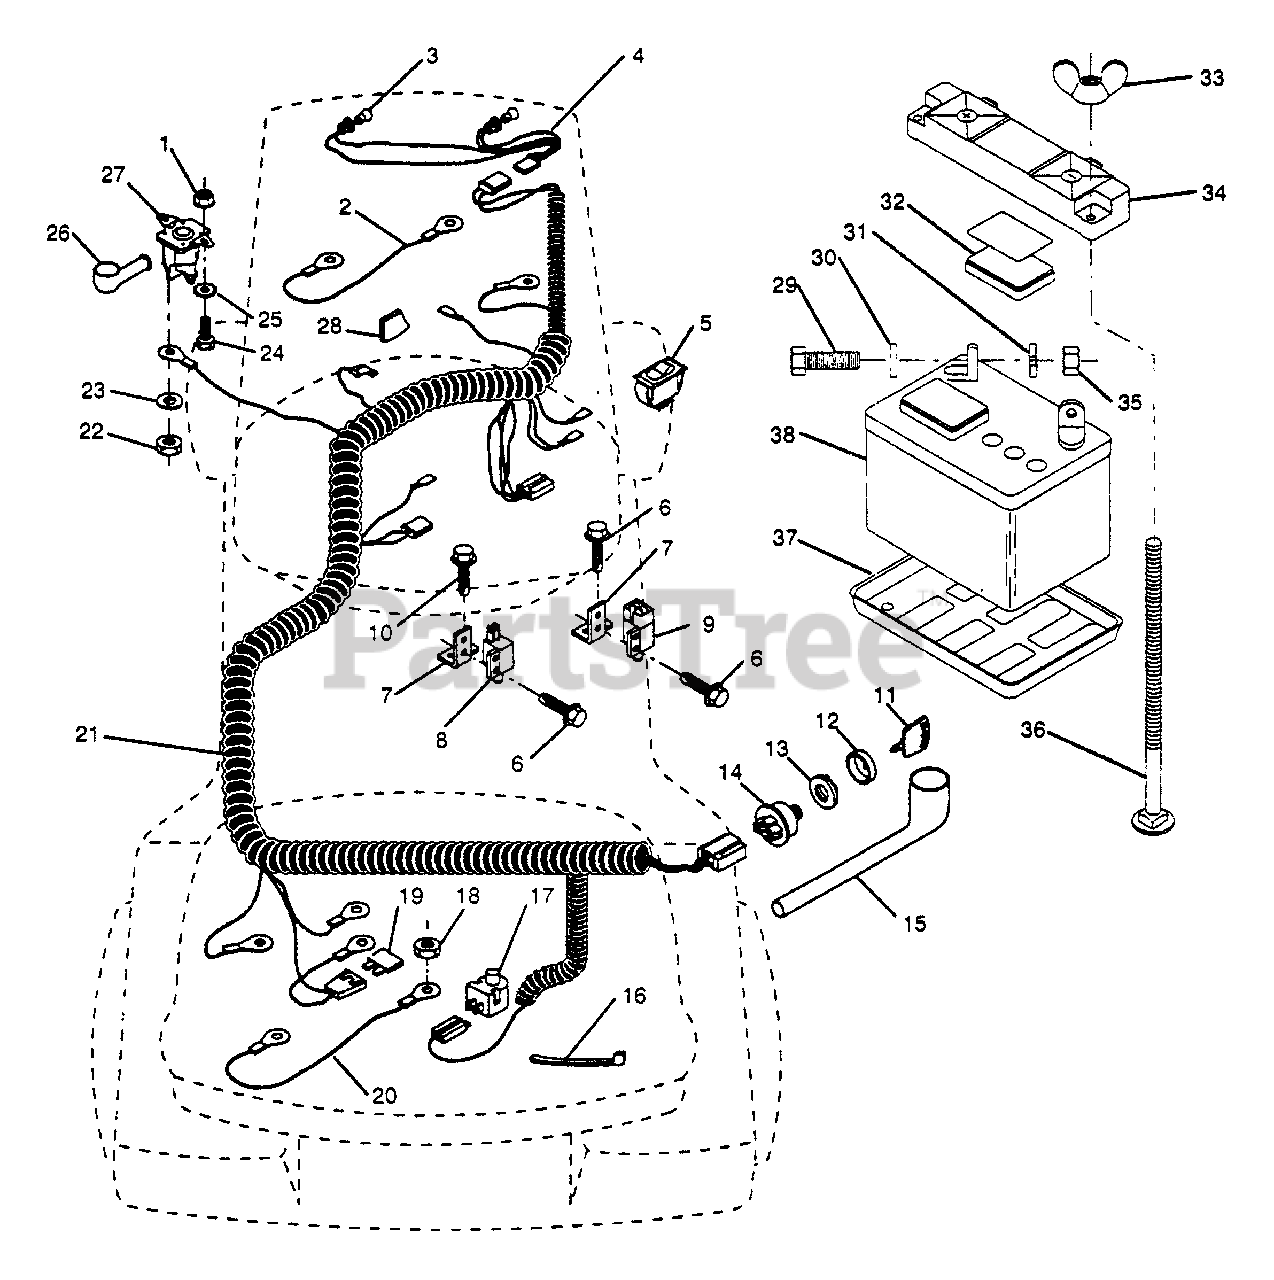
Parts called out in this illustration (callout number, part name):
1	Nut, Hex Keps 1/4-20
2	Assembly, Cable
3	Bulb, Light
4	Harness, Light Socket
5	Switch, Light
6	Screw, Tap Hex #10-24 x 1/2
7	Bracket, Switch
8	Switch, Interlock (Clutch/Brake)
9	Switch, Interlock (Attachment)
10	Screw, Hex Wsh. Tap #10-16 x 1/2
11	Key, Molded
12	Cover, Key Ignition
13	Nut, Ignition
14	Switch, Ignition
15	Cover, Ignition Switch
16	Tie, Cable
17	Switch, Plunger
18	Nut Keps 5/16-18
20	Assembly, Cable
21	Harness, Ignition
22	Nut, Hex Jam 1/4-20
23	Washer, Lock 1/4
24	Bolt, Fin. Hex 1/4-20 UNC x 1/2 Gr.5
25	Washer. Lock Ext. Tooth 1/4
26	Cover, Terminal
27	Solenoid
28	Stop, Choke
29	Bolt, Hex 1/4-20 UNC x 3/4
30	Washer 9/32 x 5/8 x 16 Ga.
31	Washer, Lock Hvy. Helical Spring 1/4
32	Cap, Battery
33	Nut, Wing, Plastic, Locking 1/4-20
34	Guard, Terminal
35	Nut, Fin. Hex 1/4-20 UNC
36	Bolt, Carriage 1/4-20 UNC x 7-1/2
37	Tray, Battery
38	Battery
